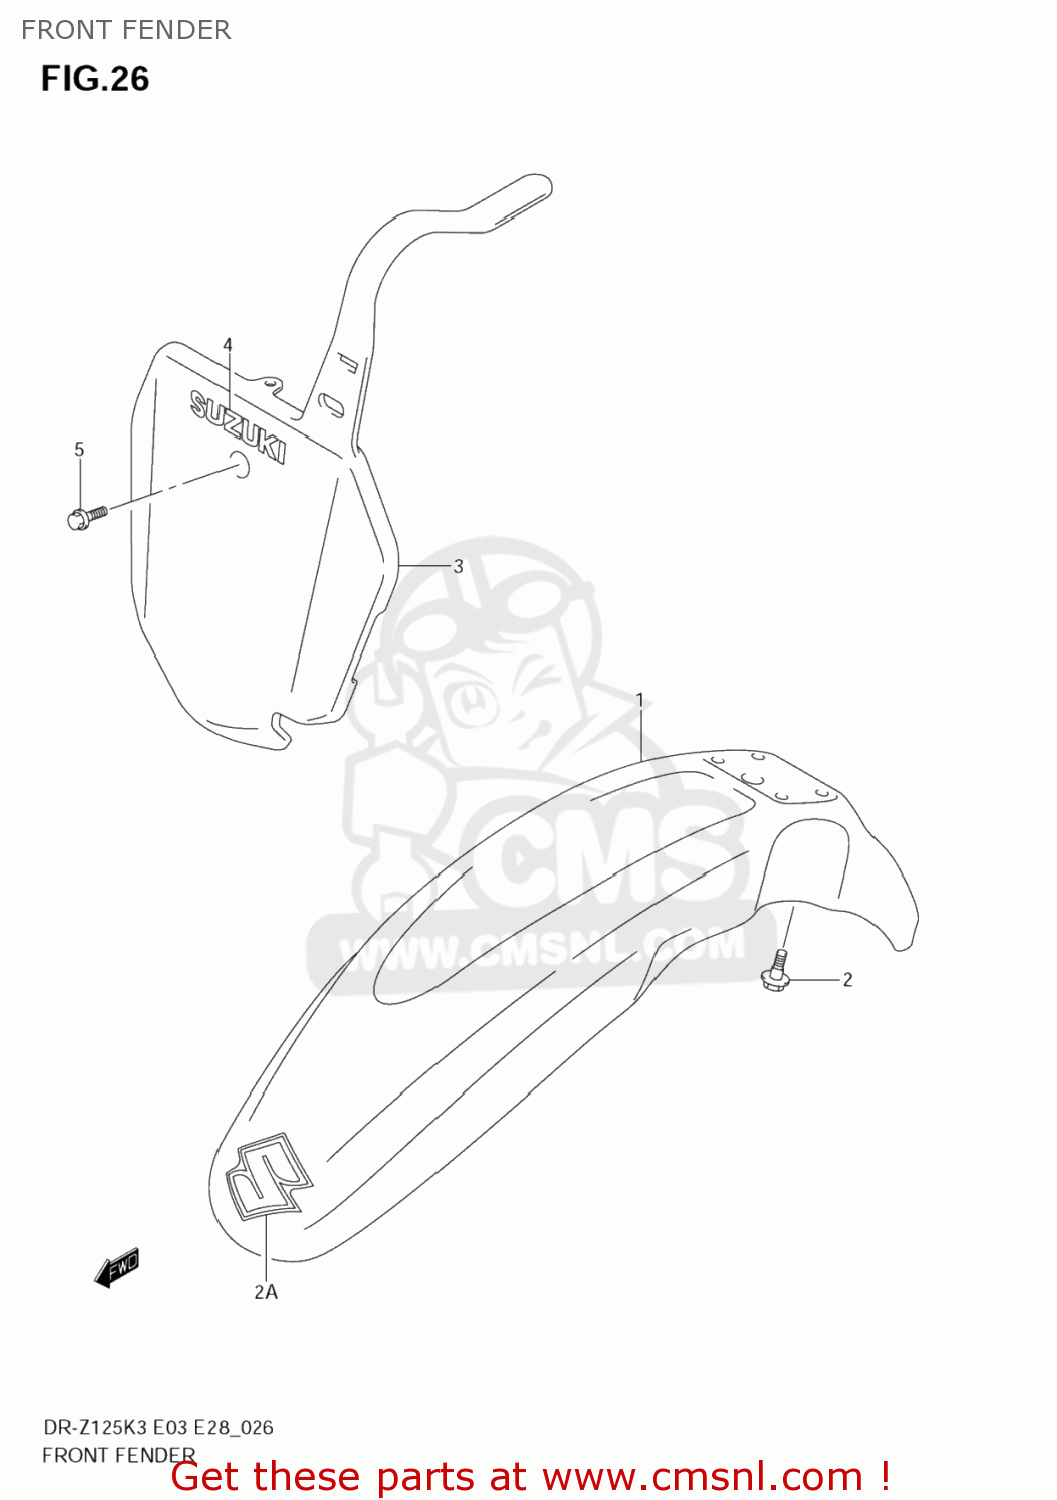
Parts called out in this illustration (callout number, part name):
1	FENDER,FR
2	SCREW(6X18)
2A	EMBLEM,S
3	PLATE,NUMBER FR
4	EMBLEM,SUZUKI
5	SCREW
